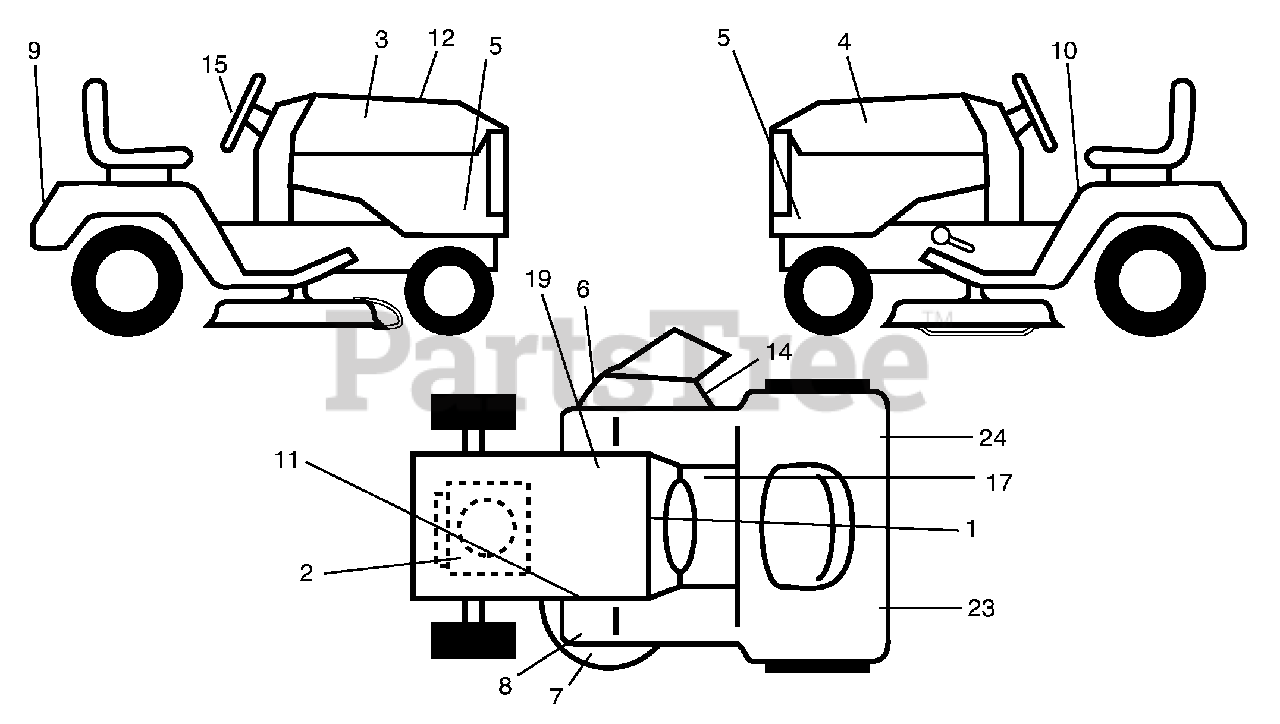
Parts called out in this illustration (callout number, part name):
1	Decal, Dash
3	Decal, Hood, RH
4	Decal, Hood, LH
5	Decal, Hood Sides
6	Decal, Warning
7	Decal, Upstop
8	Decal, Deck Caution
9	Decal
10	Decal, Danger
11	Ft. Rest
12	Decal, Repl.
14	Decal, V-Belt Schematic
15	Decal, Ins. Whl. Strg.
17	Decal, Saddle Brake Parking
19	Decal, Battery
23	Reflector, LH
24	Reflector, RH
